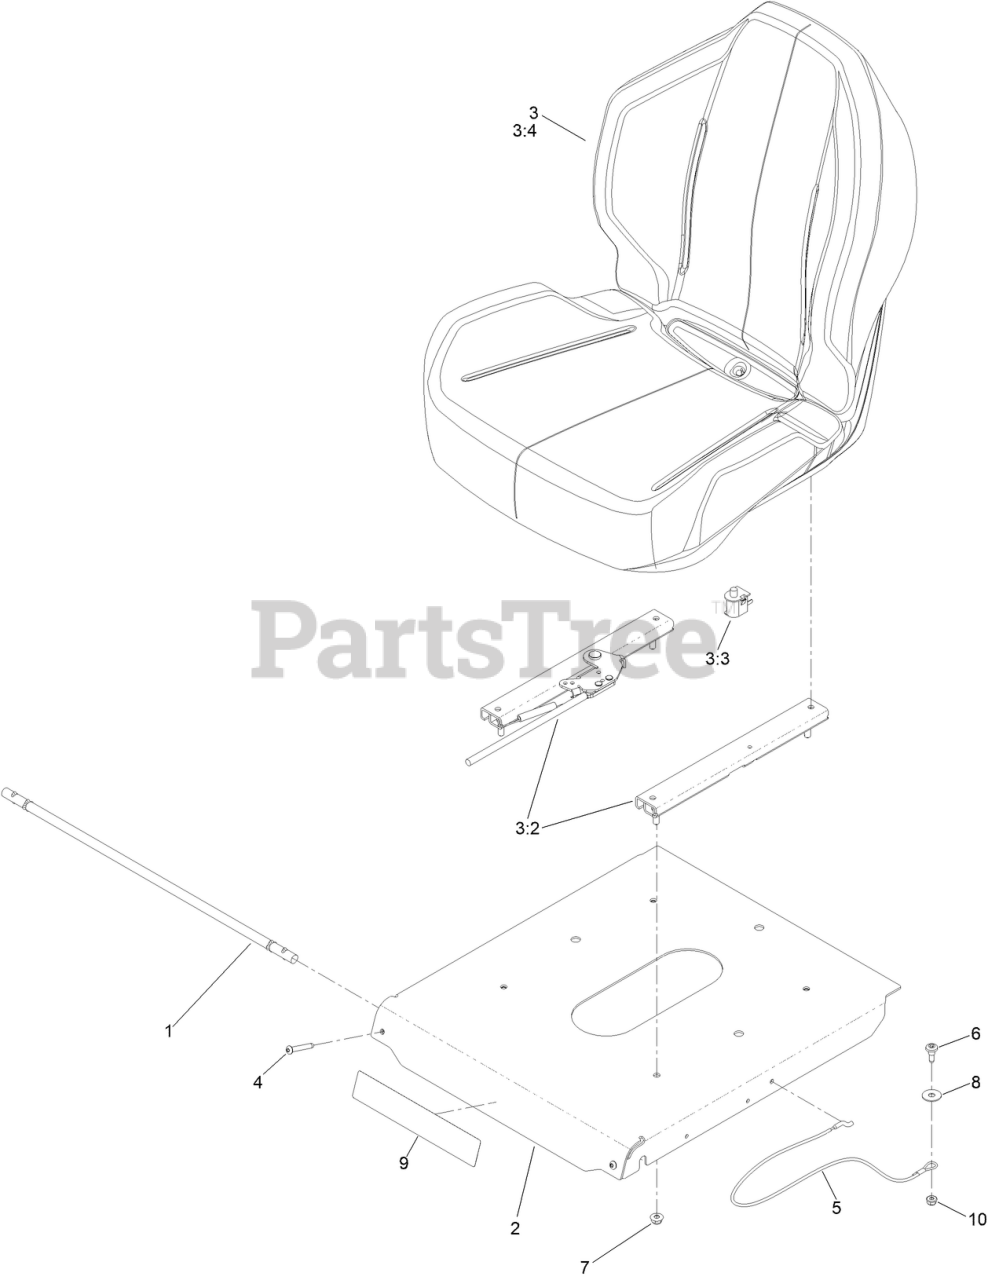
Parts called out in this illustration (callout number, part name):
1	ROD-PIVOT
2	PAN-SEAT
3	SEAT ASM - MILSCO CS180D
3:2	KIT-ADJUSTER
3:3	SWITCH-BAIL
3:4	COVER-SEAT
4	SCREW-TBH,THD ROLL
5	CABLE-LANYARD, 26.75"
6	SCREW-SHOULDER
7	NUT-HF
8	WASHER-FLAT
9	DECAL-TITAN
10	NUT-FLANGE, NI
